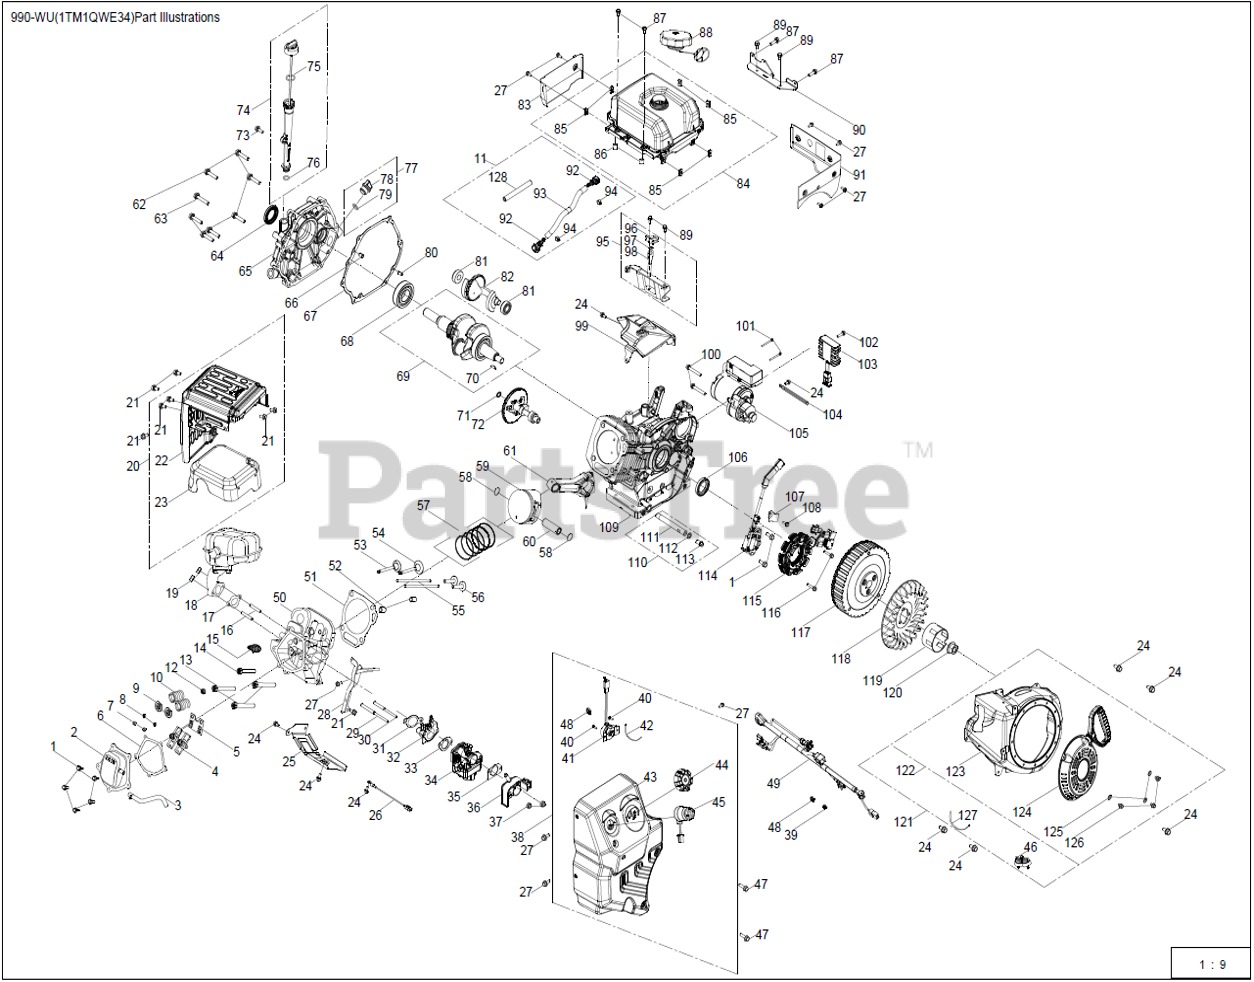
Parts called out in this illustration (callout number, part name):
1	BOLT M6 x 16
2	VALVE COVER
3	BREATHER HOSE
4	ROCKER ARM ASSEMBLY
5	PUSH ROD GUIDE
6	VALVE COVER GASKET
7	EXHAUST VALVE ADJUSTER
9	VALVE SPRING SEAT
10	SPRING VALVE
11	FUEL LINE ASSEMBLY
12	INTAKE VALVE SEAL
13	SCREW M10-1.25 x 87 x GR10.9
14	SCREW M10-1.25 x 65 x GR10.9
15	SPARK PLUG (F6RTC/RN11YC/BPR6ES)
16	STUDS M8-1.25 x 48.5
17	MUFFLER GASKET
20	MUFFLER SHIELD
21	BOLT M6-1 x 10 GR8.8
22	MUFFLER SHIELD (OUTER)
23	MUFFLER SHIELD (INNER)
24	BOLT M6-1 x 12 GR8.8
25	CYLINDER BAFFLE
26	TEMP SENSOR
27	BOLT M6-1 x 14 GR8.8
28	RECOIL SNOW GUARD
29	STUD M6 x 123
30	STUD M6-1 x 104
31	CARBURETOR INSULATOR GASKET
33	CARB GASKET
34	FUEL INJECTOR
35	AIR FILTER GASKET
36	HEATER BOX
38	CONTROL PANEL
39	FUEL LINE SUPPORT CLAMP
41	SPEED CONTROL SWITCH
43	CONTROL PANEL
44	SPEED CONTROL KNOB
45	KEY SWITCH
47	SCREW M6-1 x 20 CL5.8
48	WIRE SUPPORT CLAMP
49	WIRE HARNESS
50	CYLINDER HEAD
51	HEAD GASKET
52	DOWEL PIN 12x20
53	EXHAUST VALVE
54	INTAKE VALVE
57	PISTON RING SET
58	PISTON PIN SNAP RING
61	CONNECTING ROD ASSEMBLY
62	SCREW M8-1.25 x 38 GR10.9
63	BOLT M8 x 45
65	CRANKCASE COVER
67	CRANKCASE COVER GASKET
68	BALL BEARING
69	CRANKSHAFT ASSEMBLY
70	WOODRUFF KEY
73	BOLT M6-1 x 18 GR8.8
74	DIPSTICK OIL ASSEMBLY
77	OIL DRAIN PLUG
78	OIL PLUG
80	DOWEL PIN
81	BALL BEARING
82	BALANCE GEAR ASSEMBLY
83	FUEL TANK BACK PANEL
85	THREADED TAB
89	BOLT M8-1.25 x 14 GR8.8
90	FUEL TANK BASE BRACKET
91	FUEL TANK FRONT PANEL
92	QUICK DISCONNECT FUEL LINE
93	FUEL HOSE 8 x 14 x 290
95	FUEL TANK MOUNTING BRACKET
96	RUBBER GROMMET
97	RUBBER GROMMET
98	FUEL TANK MOUNTING BRACKET
99	GOVERNOR GEAR BRACKET
100	BOLT M8-1.25 x 55 GR8.8
102	BOLT M6-1 x 25 GR8.8
104	SUPPORT CLAMP
105	ELECTRIC STARTER
107	ALTERNATOR WIRE CLAMP BRACKET
108	BOLT M6-1 x 8 GR8.8
110	OIL DRAIN PIPE
111	OIL DRAIN PIPE
112	FLAT WASHER
113	OIL DRAIN PLUG
114	IGNITION COIL (RUBBER BOOT)
115	CHARGING COIL
116	BOLT-M6-1 x 30 GR8.8
118	COOLING FAN
119	STARTER CUP
120	FLYWHEEL NUT M16X1.5
121	Not Serviceable/ Components Only
122	RECOIL START
123	BLOWER HOUSING
124	RECOIL START ASSEMBLY
125	FLAT WASHER
126	BOLT M6 x 10
127	CABLE TIE - 3 x 150
128	PROTECTIVE FOAM TUBE
